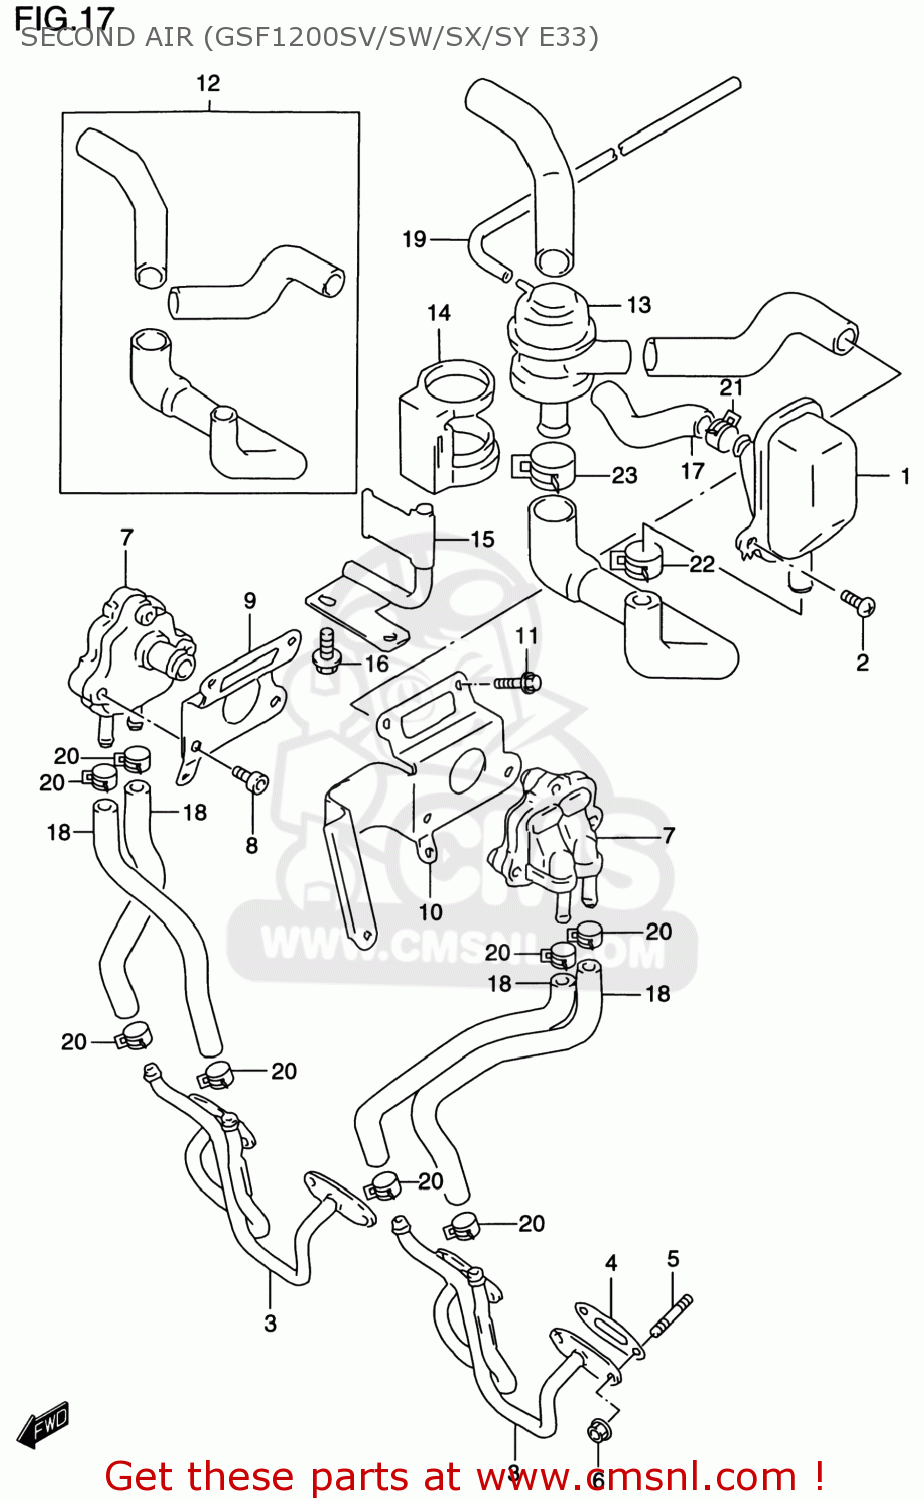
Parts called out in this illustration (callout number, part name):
1	CLEANER ASSY,2ND AIR
2	SCREW
3	PIPE,2ND AIR,L
4	GASKET,SECOND AIR PIPE (NAS)
5	STUD BOLT
6	NUT
7	VALVE ASSY,2ND AIR REED
8	BOLT
9	BRACKET,REED VALVE,RIGHT
10	BRACKET COMP,REED VALVE
11	BOLT
12	HOSE SET,SECOND AIR
13	VALVE ASSEMBLY,SECOND AIR SWITCH
14	CUSHION,2ND AIR VALVE
15	BRACKET COMP,SECOND AIR S
16	BOLT
17	HOSE(12X16X600)
18	HOSE(9X14X600)
19	HOSE(4X7X600)
20	CLIP
21	CLIP
22	CLIP
23	CLIP
